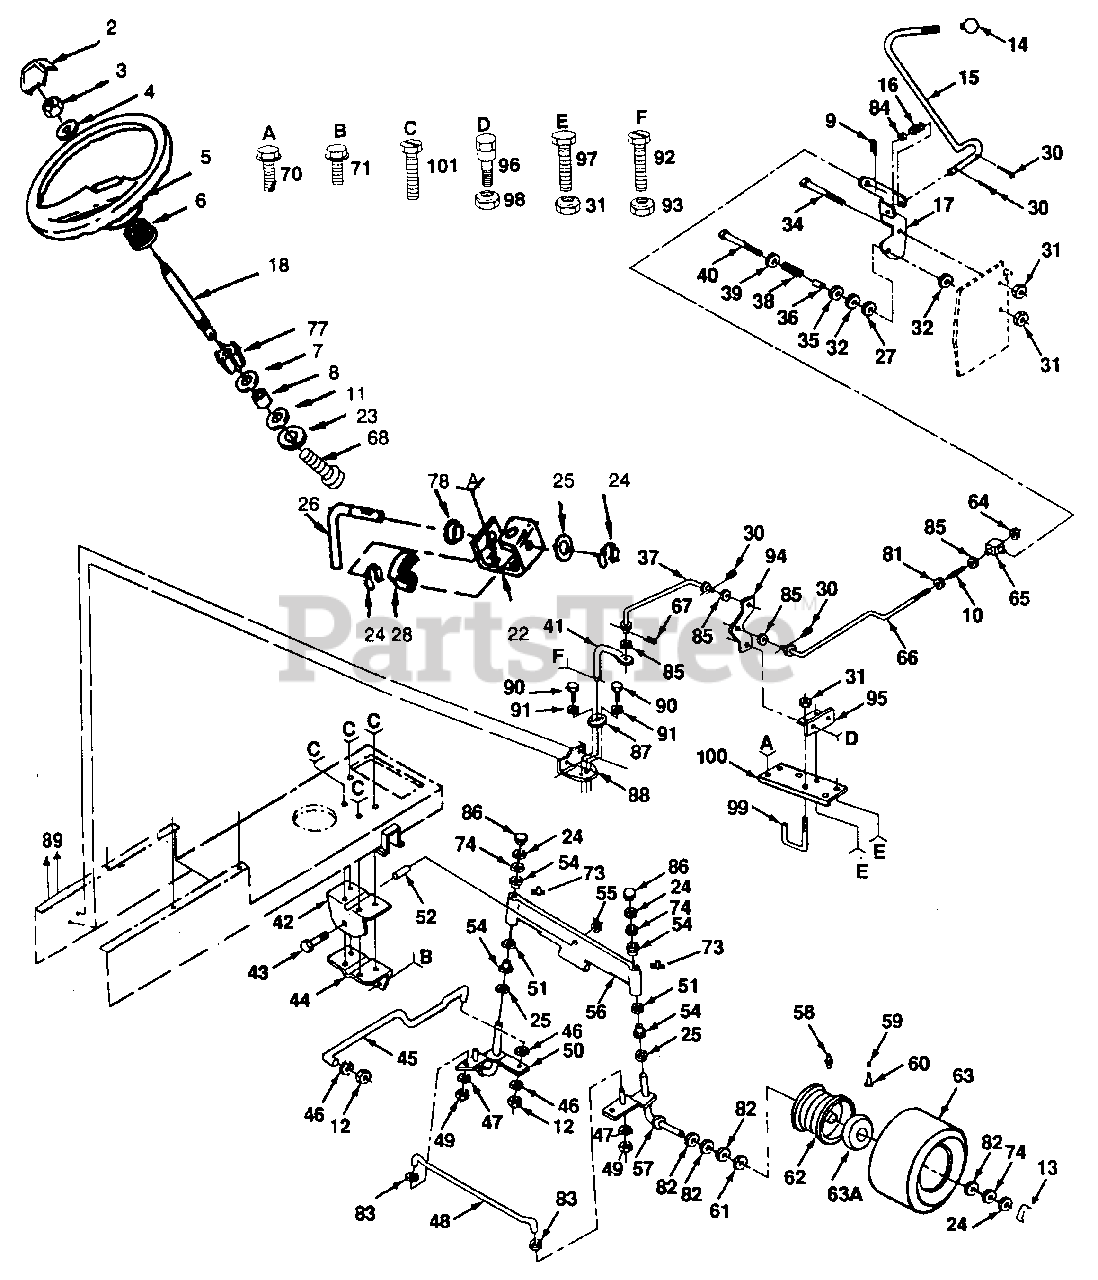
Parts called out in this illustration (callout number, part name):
2	Insert, Steering Wheel
3	Nut, Hex 3/4-16
5	Wheel, Steering
6	Adapter, Steering Wheel
8	Support, Shaft
9	Retainer Spring
10	Spring, Compression
11	Washer, Shim 1/4 X 5/8 X .062
12	Nut, Fin Hex 3/8-24 UNF
14	Knob, Gearshift
16	Spring, Torsion
17	Bracket, Control Rod
18	Shaft, Steering
22	Bracket, Steering
23	Washer, Lock, Heavy. Helical Spring 1/4
25	Bearing, Thrust
26	Shaft, Pitman
27	Washer, Phenolic
28	Gear, Sector
30	Pin, Cotter 1/8 x 3/4
31	Locknut 3/8-16
32	Washer, Friction
34	Bolt, Shoulder 3/8-16 x 1-3/8
35	Washer 21/32 x 1-1/4 x 16 Gauge
37	Link, Control
38	Spring, Compression
39	Washer 13/32 x 1-1/4 x 12 Ga.
40	Bolt, Hex 3/8-16 x 3
41	Lever, Pump Control
42	Support, Saddle, Rear
43	Bolt Hex 5/8-11 x 3-3/4
44	Support, Saddle, Front
45	Link Drag
46	Washer, Lock 3/8
47	Washer, Lock 5/16
48	Rod, Tie
49	Nut, Hex 5/16-24
50	Spindle L.H.
51	Washer 27/32 x 1-1/4 x 16 Ga.
52	Spacer
54	Bearing
55	Locknut, Flange 5/8-11
57	Spindle, R H
58	Fitting, Grease
62	Rim, 6" Front
63	Tire, Front
64	Nut, Hex Jam 3/8-16
66	Rod, Control, Adjustable
67	Clip, Hairpin
68	Screw, Socket Hex 1/4-20 X 5/8
70	Screw, Hex Washer Head Threaded, Rolling 3/8-16 x 3/4
71	Screw, Hex Washer Head Threaded, Rolling 5/16-18 x 1/2
74	Washer 25/32 x 1-5/8 x 16 Ga.
78	Nyliner, Snap - In
81	Washer 13/32 x 3/4 x 12 Gauge
82	Washer 25/32 x 1 1/4 x 16 Gauge
83	Washer 11/32 x 3/4 x 16 Gauge
84	Washer 15/32 x 15/16 x 16 Gauge
85	Washer, Spring
87	Guide. Control
88	Bracket, Guide, Control
89	Screw, Hex Washer Head Threaded, Rolling 5/16-18 x 3/4 Type TT
90	Screw, Hex Head Tapping #10-24 UNC x 1/2 Type - T
91	Washer 7/32 x 1/2 x 16 Ga.
92	Bolt 10-24 x 3/4
93	Locknut #10-24 UNC
95	Bracket, Bellcrank Pivot
96	Bolt, Shoulder
97	Bolt, Fin Hex 3/8 UNC-16 x 1
98	Locknut 5/16-18
99	Keeper, Centerspan
100	Bracket, Chassis, Reinforcement, Hydro
101	Screw, Special 3/8-16 X 3/4
